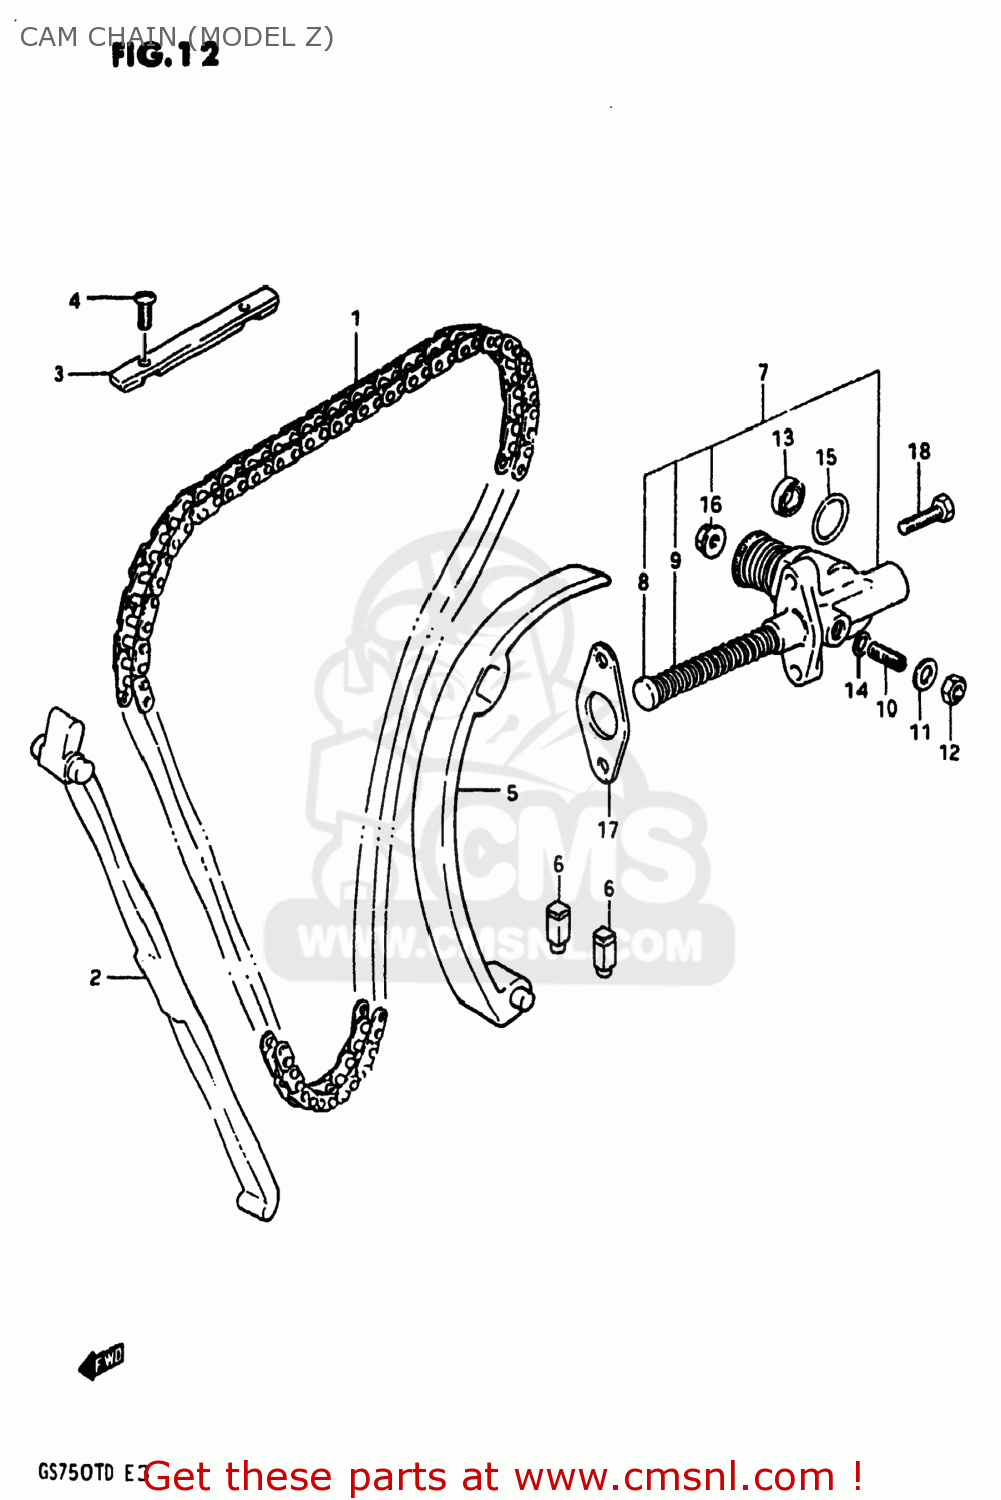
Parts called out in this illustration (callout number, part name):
1	CHAIN,CAMSHAFT DRIVE
2	GUIDE,CAM CHAIN NO.1
3	GUIDE,CAM CHAIN NO.3
4	SCREW
5	TENSIONER,CAM CHAIN
6	CUSHION,CAM CHAIN TENSIONER
7	ADJUSTER ASSEMBLY,TENSIONER
8	ROD,PUSH
9	SPRING
10	SCREW
11	WASHER
12	NUT
13	SEAL,OIL(10X16X4)
14	O RING(D:1.9,ID:5.7)
15	O RING(D:2.4,ID:20.8)
16	NUT
17	GASKET,TENSIONER ADJUSTER (MCA)
18	SCREW (6X25)
